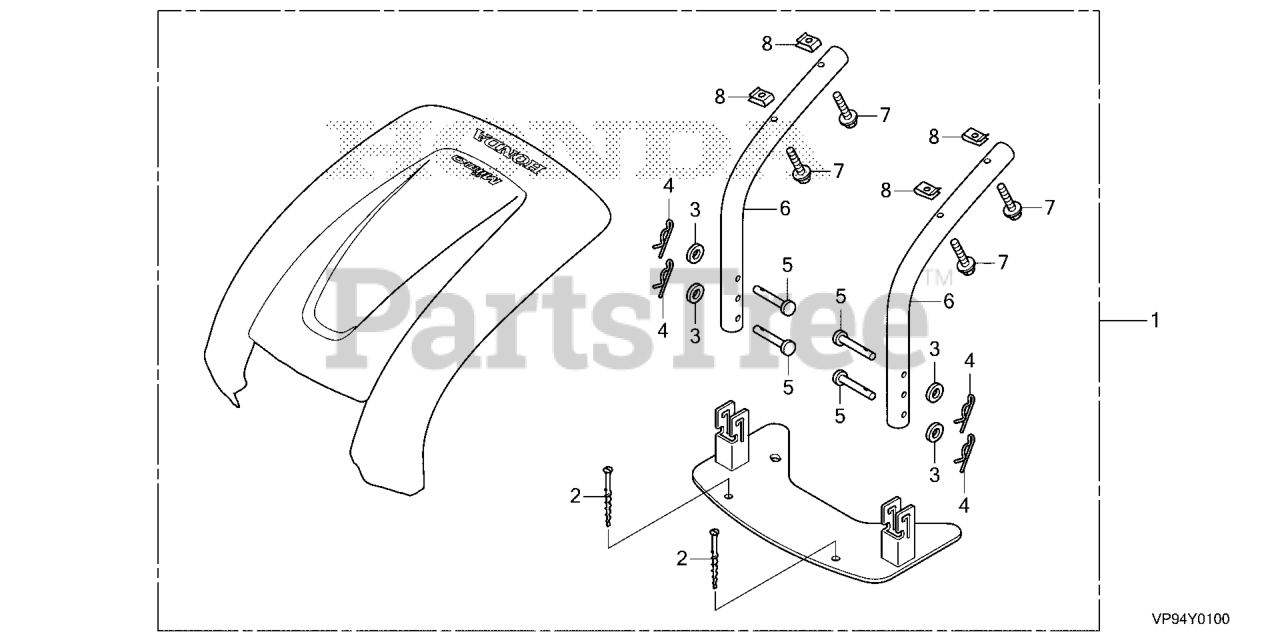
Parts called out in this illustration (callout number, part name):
1	ROOF KIT, STATION
2	PEG, STATION
3	WASHER, PLAIN (6MM)
4	PIN, LOCK (6MM)
5	PIN, PITCH STEP
6	PIPE, HINGE
7	BOLT, FLANGE (6X35)
8	NUT, CLIP (6MM)
